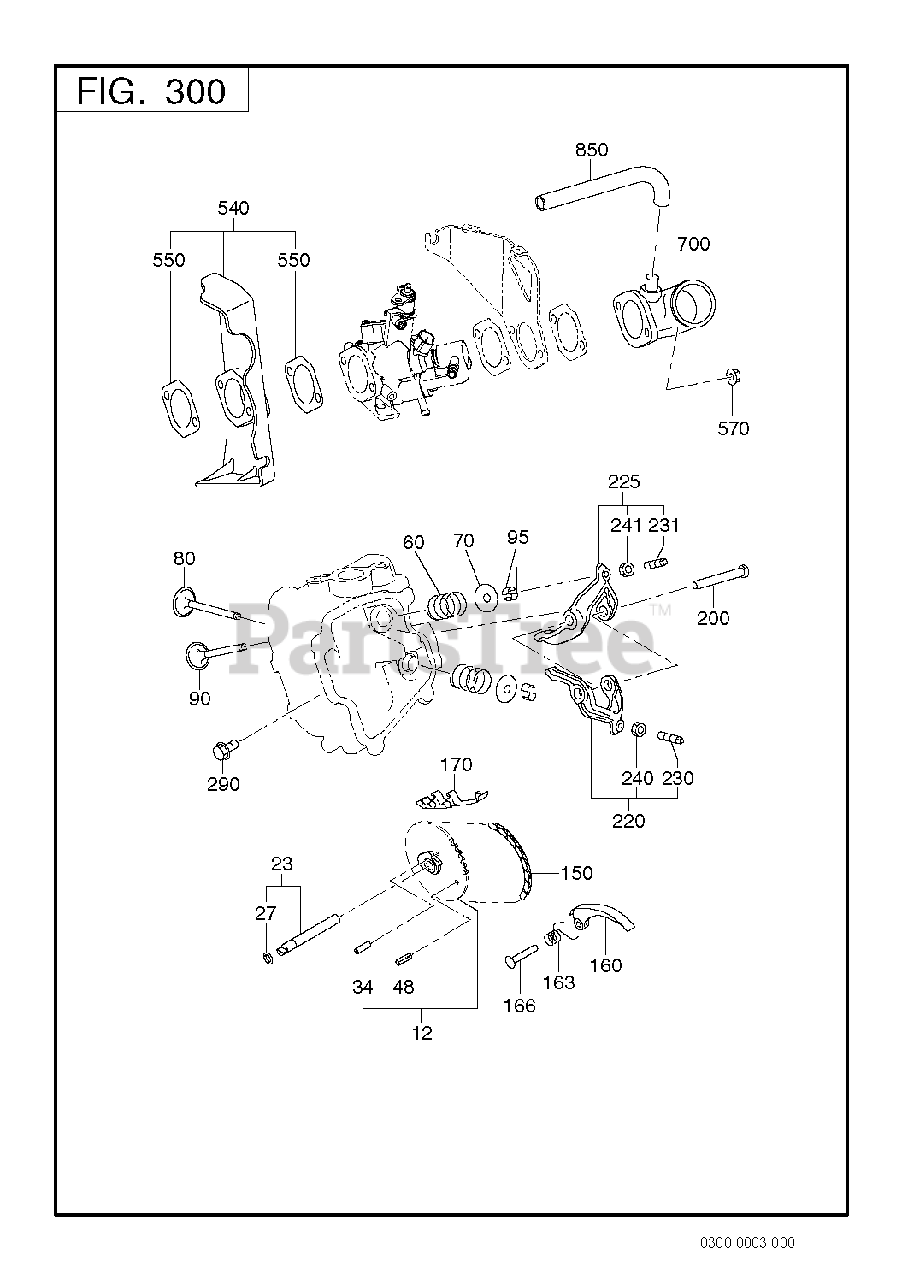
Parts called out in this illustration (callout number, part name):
23	PIN (CAM SHAFT) CP
70	SPRING RETAINER
95	COLLET-VALVE
150	TIMING CHAIN CP
163	SPRING(TENTIONER)
166	PIN(TENTIONER)
220	ROCKER ARM (IN) AY
225	ROCKER ARM (EX)
700	ADAPTER (AIR INTAKE)
